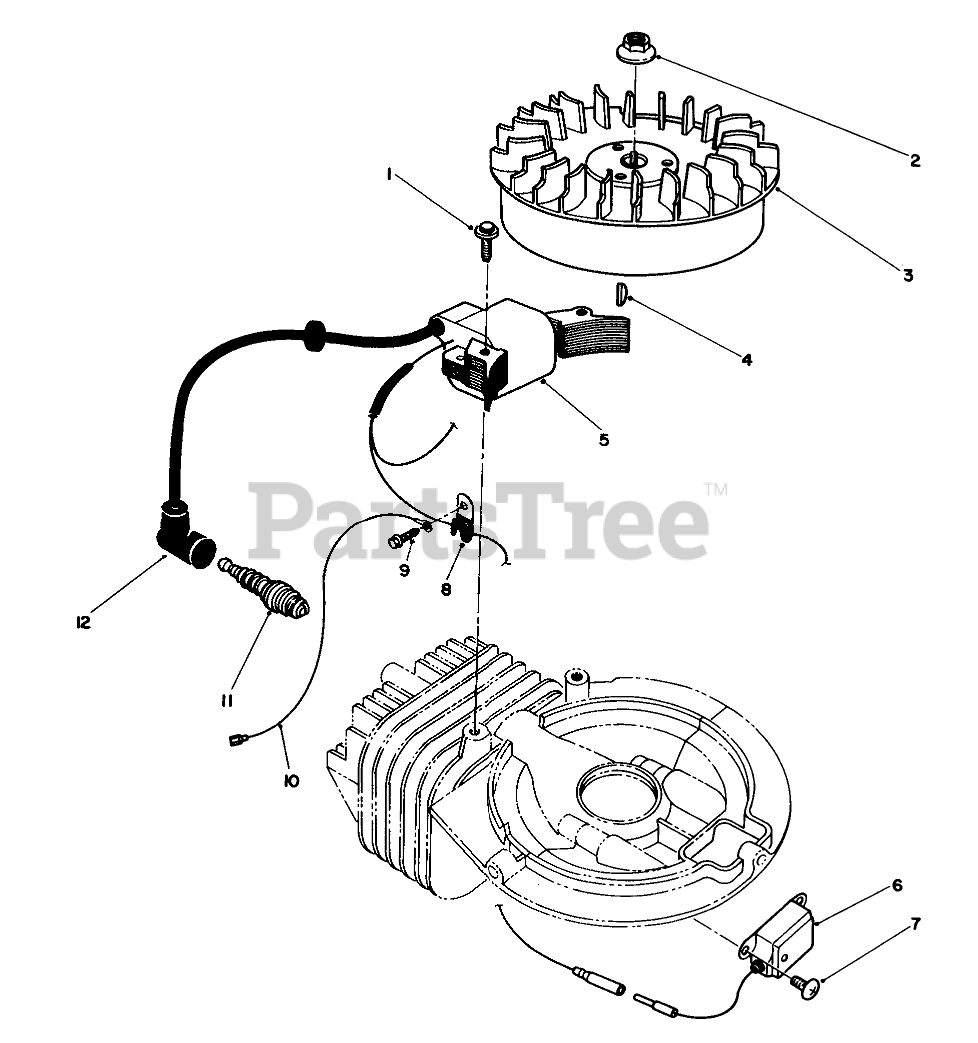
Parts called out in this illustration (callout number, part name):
1	SCREW
3	FLYWHEEL
5	MAGNETO COIL
6	MAGNETO MODULE
7	SCREW
8	CLAMP
11	Sparkplug
12	CAP-SPARKPLUG
